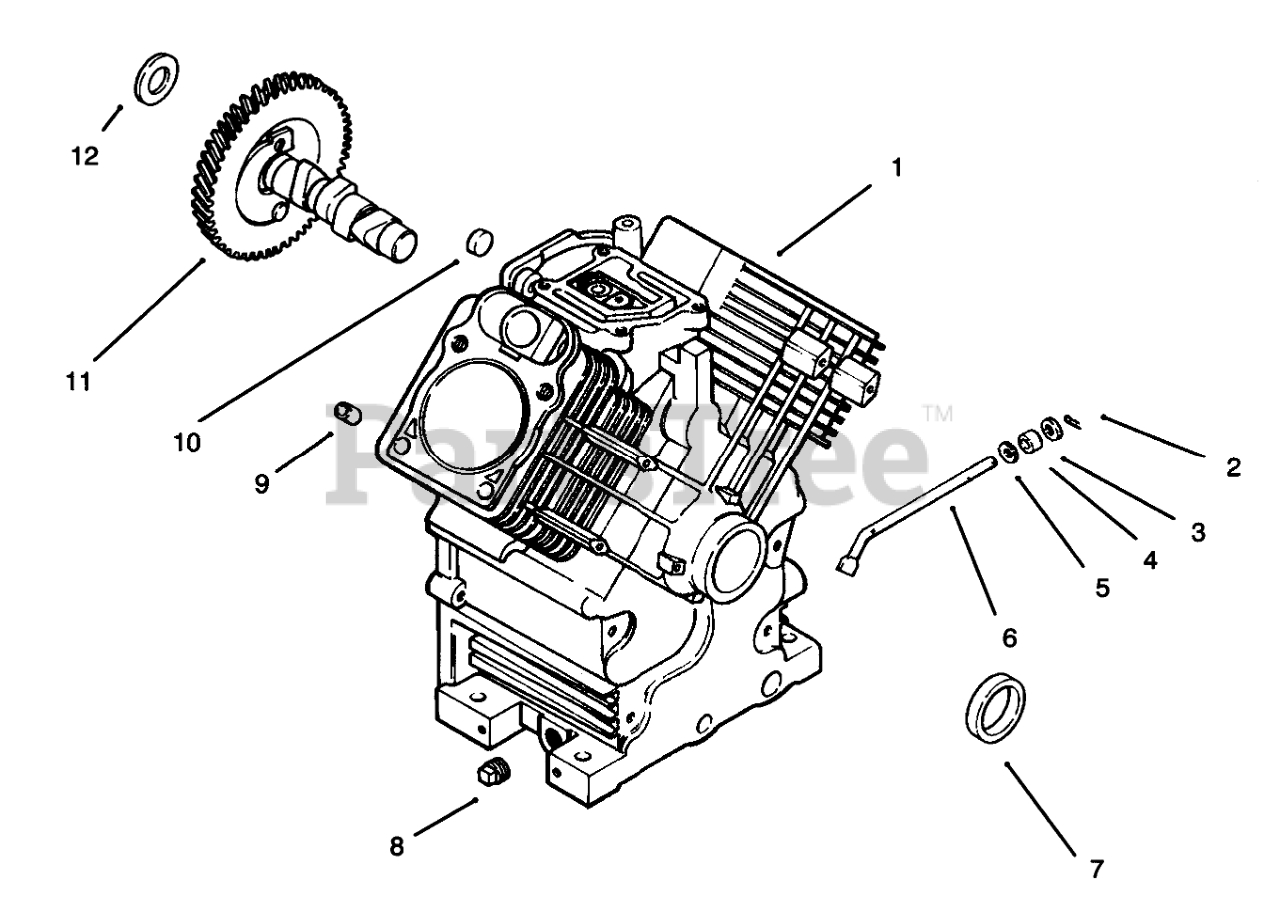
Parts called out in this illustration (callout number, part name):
2	Pin-Hitch
3	Washer
4	Seal
5	Washer
6	Shaft-Governor Cross
7	Seal-Oil
8	Plug
9	Pin-Dowel
11	Camshaft
12	Shim-Camshaft
